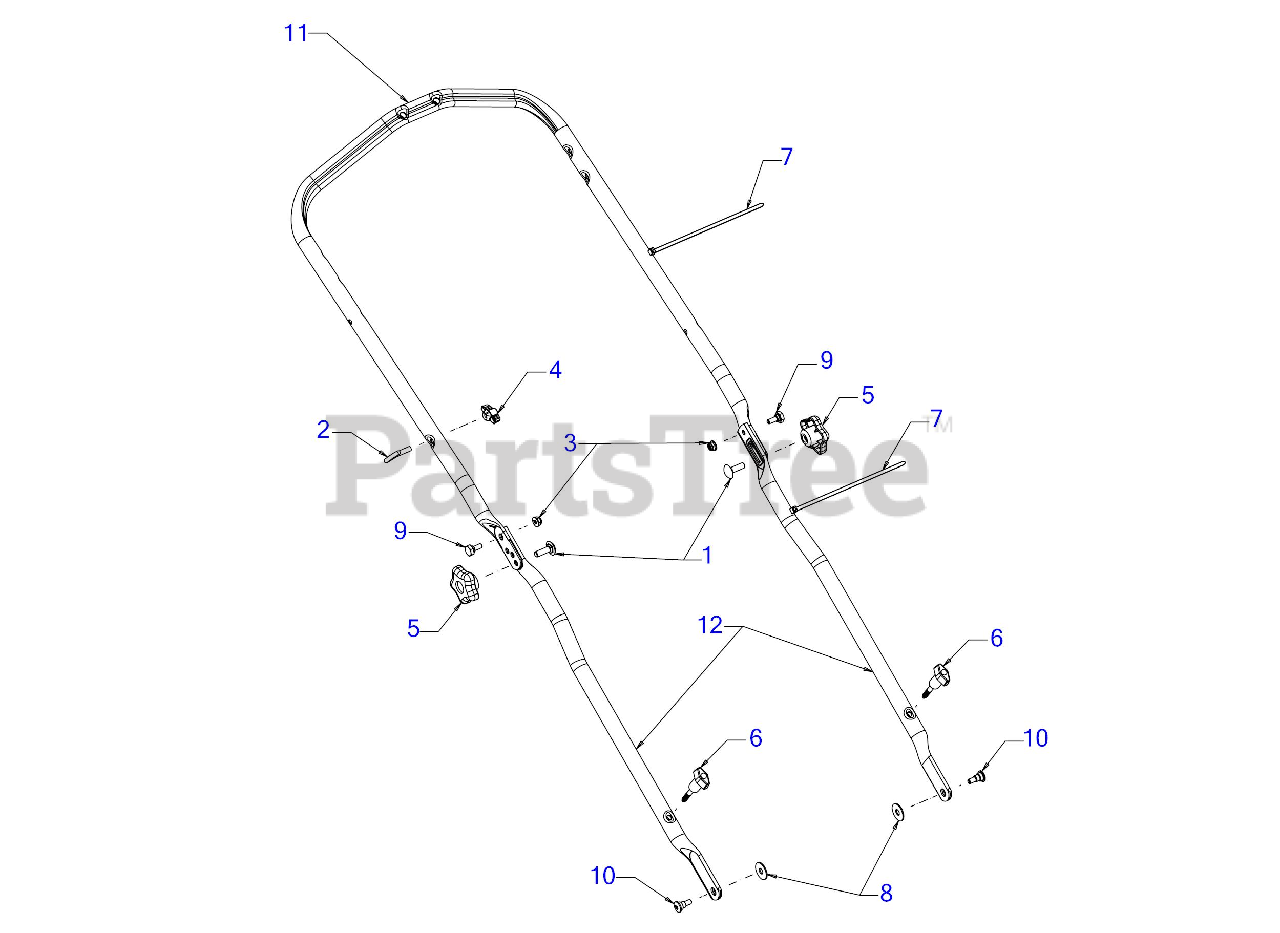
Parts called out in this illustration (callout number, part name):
1	SCREW 5/16-18 x 1.00 GR5
2	EYEBOLT 1/4-20
3	FLANGE LOCK NUT
4	HANDLE KNOB
5	STAR KNOB 5/16-18
6	WING KNOB 1/4-20
7	7" CABLE TIE
8	FLAT WASHER 344X1.00
9	SHOULDER SCREW
10	SHOULDER SCREW .450X .188X 1/4-20
11	UPPER ERGO HANDLE
12	LOWER HANDLE
